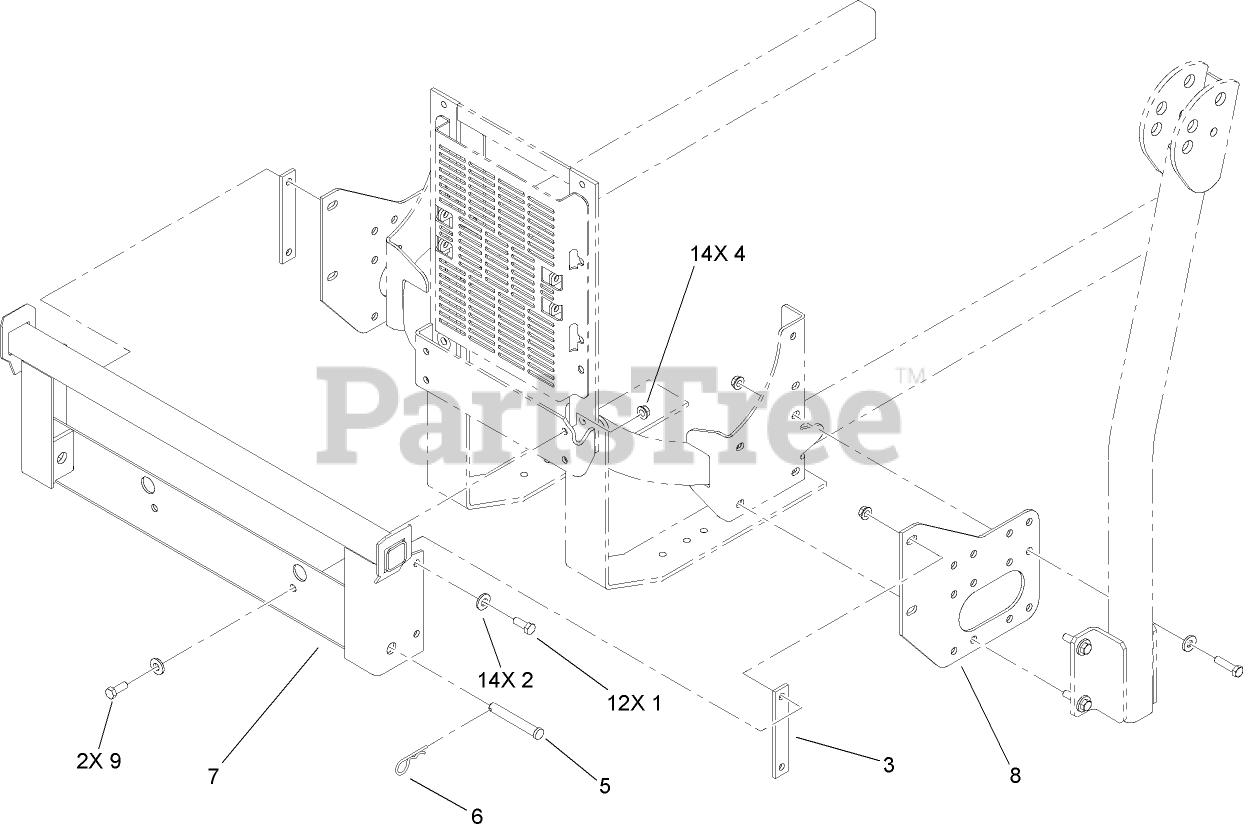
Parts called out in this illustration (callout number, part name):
1	SCREW-HH
2	WASHER-BELLEVILLE
4	NUT-HHF, WHIZ
5	PIN-CLEVIS
6	PIN-COTTER
7	MOUNT-BAGGER
8	PLATE-MOUNT, BAGGER
9	SCREW-HH
